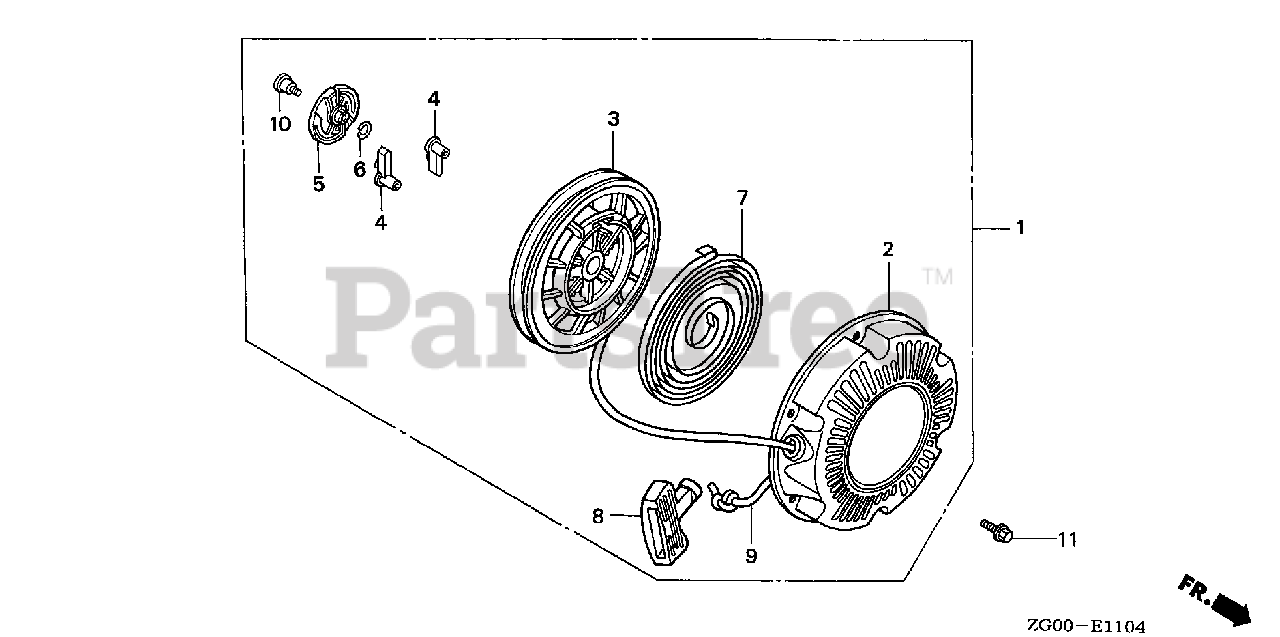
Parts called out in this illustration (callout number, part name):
1	STARTER ASSY., RECOIL *R8* (BRIGHT RED)
1	STARTER ASSY., RECOIL *R280* (POWER RED)
2	CASE, RECOIL STARTER *R8* (BRIGHT RED)
2	CASE, RECOIL STARTER *R280* (POWER RED)
3	REEL, RECOIL STARTER
4	RATCHET, STARTER
5	GUIDE, RATCHET
6	SPRING, FRICTION
7	SPRING, RECOIL STARTER
8	GRIP, STARTER
9	ROPE, RECOIL STARTER (#4X52")
10	SCREW, SETTING
11	BOLT, FLANGE (6X8)
